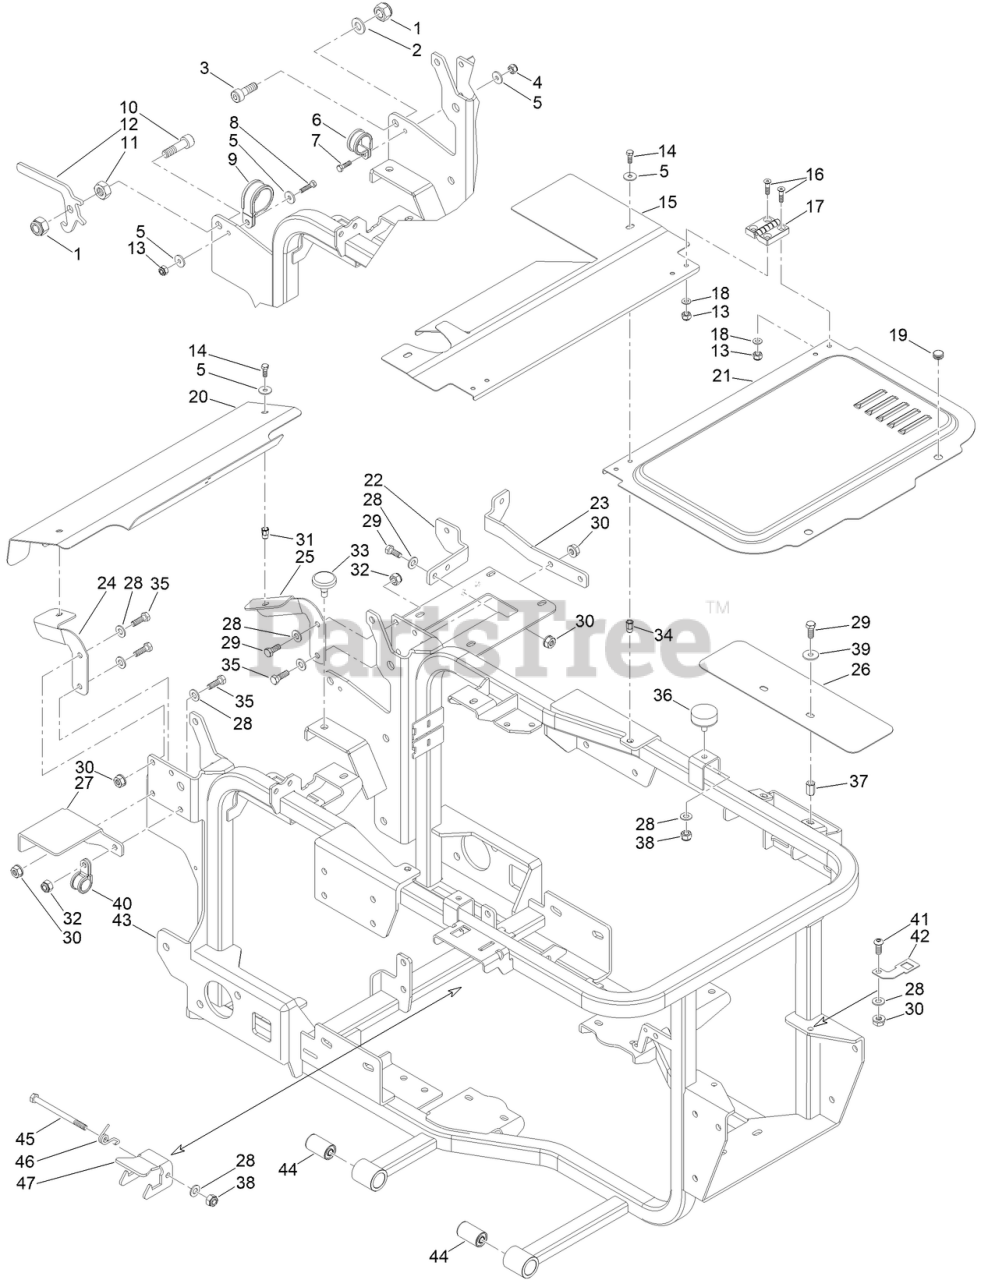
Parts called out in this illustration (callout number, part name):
2	WASHER
3	SCREW, H-SCKT CAP
5	WASHER
10	SCREW, H-SCKT CAP
12	HOOK, PLATFORM
15	COVER, ENGINE BOX
16	SCREW, H-SCKT CSK
17	HINGE-PLASTIC
18	WASHER
19	PLUG-RUBBER
20	COVER, CHUTE BOX
21	BONNET, ENGINE BOX
22	BRACKET, FAIRING SIDE
23	BRACKET, FAIRING FRONT
24	BRACKET, LH CHUTE BOX
25	BRACKET, RH CHUTE BOX
26	COVER, MUFFLER COLLECTOR
27	BRACKET, FUEL TANK
28	WASHER
31	INSERT-THREADED
33	PLUG, SHOCK-ABSORBER
34	INSERT-THREADED
36	PAD-RUBBER
37	INSERT-HEX
39	WASHER
41	SCREW, H-SCKT B HEAD
42	FUSE SUPPORT
43	CHASSIS, MAIN
44	SHOCK ABSORBER
45	SCREW-HH
46	SPRING-TORSION
47	HANDLE, RADIATOR
